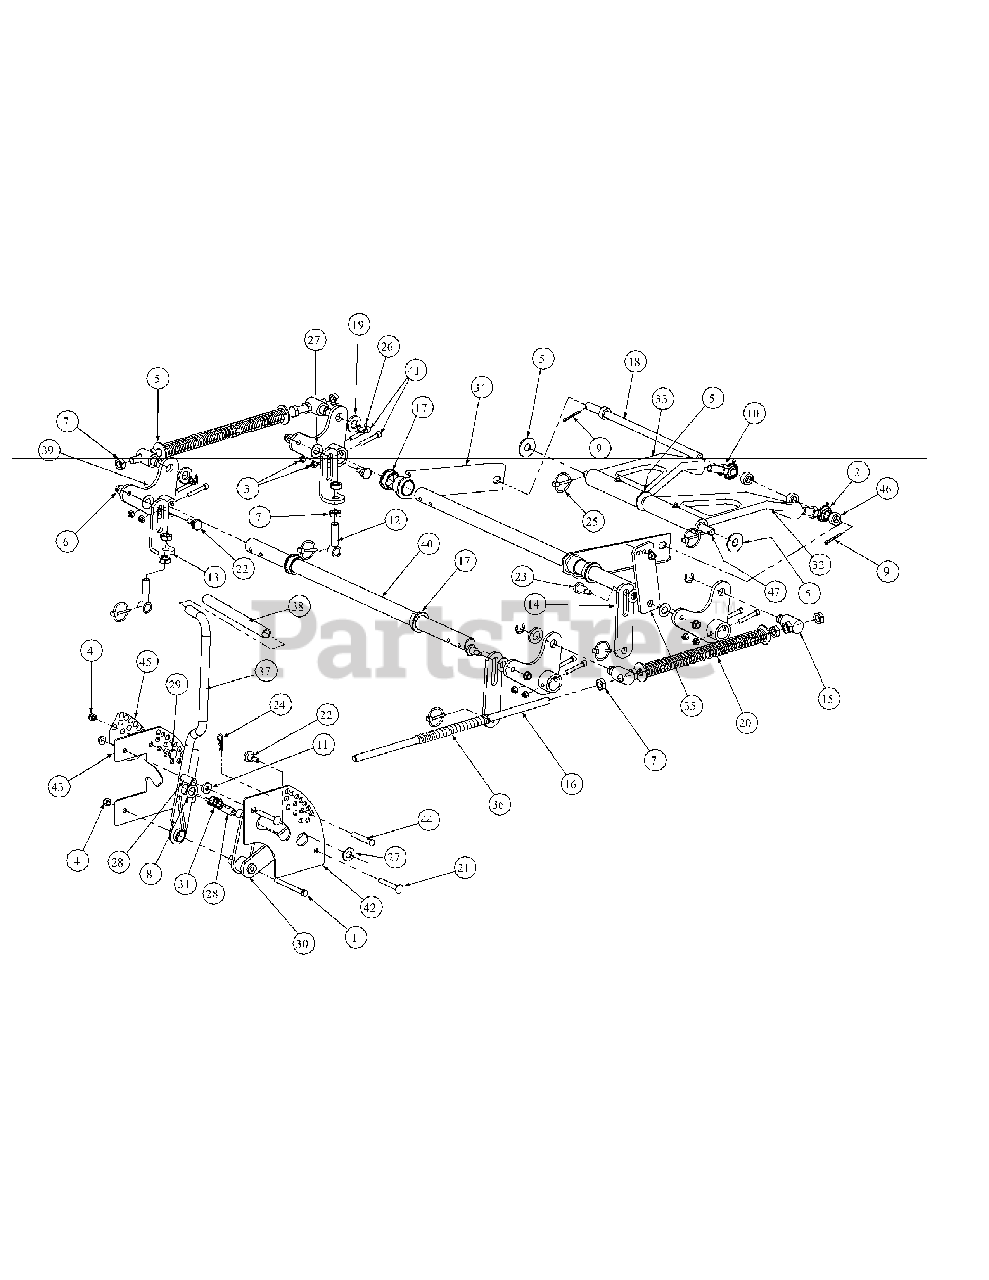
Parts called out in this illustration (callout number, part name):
1	Hex Cap Screw, 3/8-16, 3.75
2	Rod End, Male
3	Nut, 5/16-18, Nylock
4	Nylock Insert Lock Nut, 3/8-16
5	Flat Washer, 5/8
6	Hex Nut, Flange Lock, 3/8-16
7	Jam Nut, 5/8-11
8	Flat Washer, .06, .776, 1.25
9	Cotter Pin, 3/16 x 1-1
10	Jam Nut, 5/8-18
11	Idler Washer
12	Eye Bolt, 5/8ID
13	Eye Bolt Mount Link, 5/8 ID
14	Deck Link
15	Ferule Lift
16	Lift Connector Rod
17	Hex Flange Bearing, 1.25 ID
18	Front Lift Link, Rod Mount
19	Spacer, .812 ID x .268 Lg.
20	Lift Compression Spring
21	Carriage Bolt, 3/8-16, 2.75
22	Shoulder Screw, 0.625 OD x .437 Lg.
23	Shoulder Screw, 0.625 OD x .830 Lg.
24	Cotter Pin, .148 x 3.00
25	Linch Pin, 3/16 Dia.
26	E Clip, 3/4 Dia.
27	Nylon Flat Washer, 5/8
28	Spacer, .39 ID x .63 OD x 1.442
29	Shoulder Screw, .50 OD x 0.27
30	Lift Pivot Assembly
31	Lift Handle Spring
32	Bearing Lift Brace Assembly, Right Hand
33	Bearing Lift Brace Assembly, Left Hand
34	Front Frame Strut Assembly
35	Lift Link Adjustment
36	Hose, 5/8 ID 13/16 OD, 8" LG
37	Lift Handle Assembly
38	Lift Handle Grip
39	Bellecrank Weldment Assembly
40	Deck Lift Shaft
41	Socket Head Cap Screw, 5/16-18 x 2
42	Outer Lift Index Plate
43	Inner Lift Index Plate
44	Clevis Pin, .438 Dia. x 2.625 Lg.
45	Decal Height Indicator
46	Spacer, .630 ID x 1.06 OD x .440
47	Lift Link Rod
